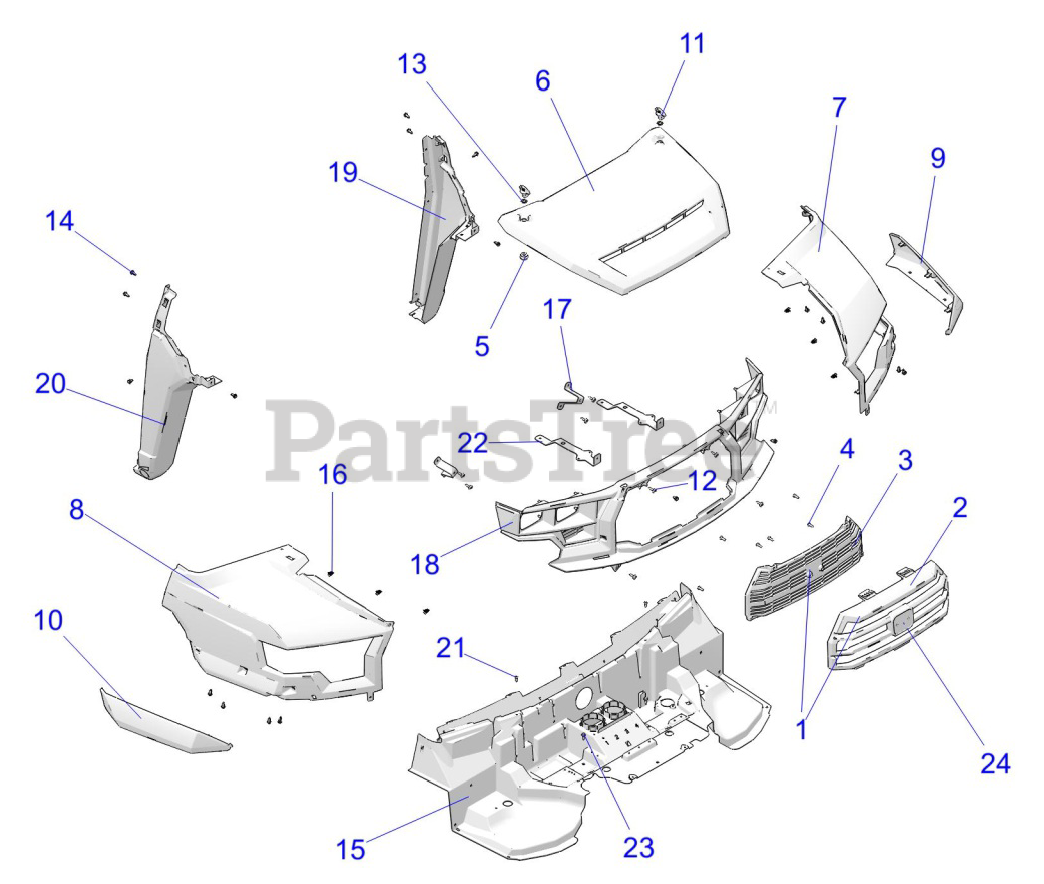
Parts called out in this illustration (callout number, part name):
1	ASM.- GRILL- GRAVELY
2	GRILL, FRONT, UPPER, BLACK
3	GRILL, UPPER, TRIM
4	SCR-TXPH-#14 X .75 HI-LO RIE
5	GROMMET-LATCH
6	HOOD-ARNS-I.RED
7	FENDER-FRONT-ARNS-LH-I.RED
8	FENDER-FRONT-ARNS-RH-I.RED
9	FLARE-FENDER-ARNS-LH-BLK
10	FLARE-FENDER-ARNS-RH-BLK
11	LATCH- 1/4 TURN
12	SCR-TXTH-M6X1.0X25 RIE
14	RIVET-TUFLOK-.315-.325X.787 (5
15	LINER-HOOD-BLK
16	CLIP- DASH TRIM METAL
18	BRKT-FASCIA MOUNT
19	BEZEL-HEADLIGHT
20	COVER-FRONT-LH-BLK
21	COVER-FRONT-RH-BLK
22	SCR-TX TRUSS-#14X3/4-HI/LO ZBK
23	BRKT-MOUNT-RADIATOR-ARNS-BLK
24	SCR-M6X1.0X20-HXHD-FLG-TDFM-BL
